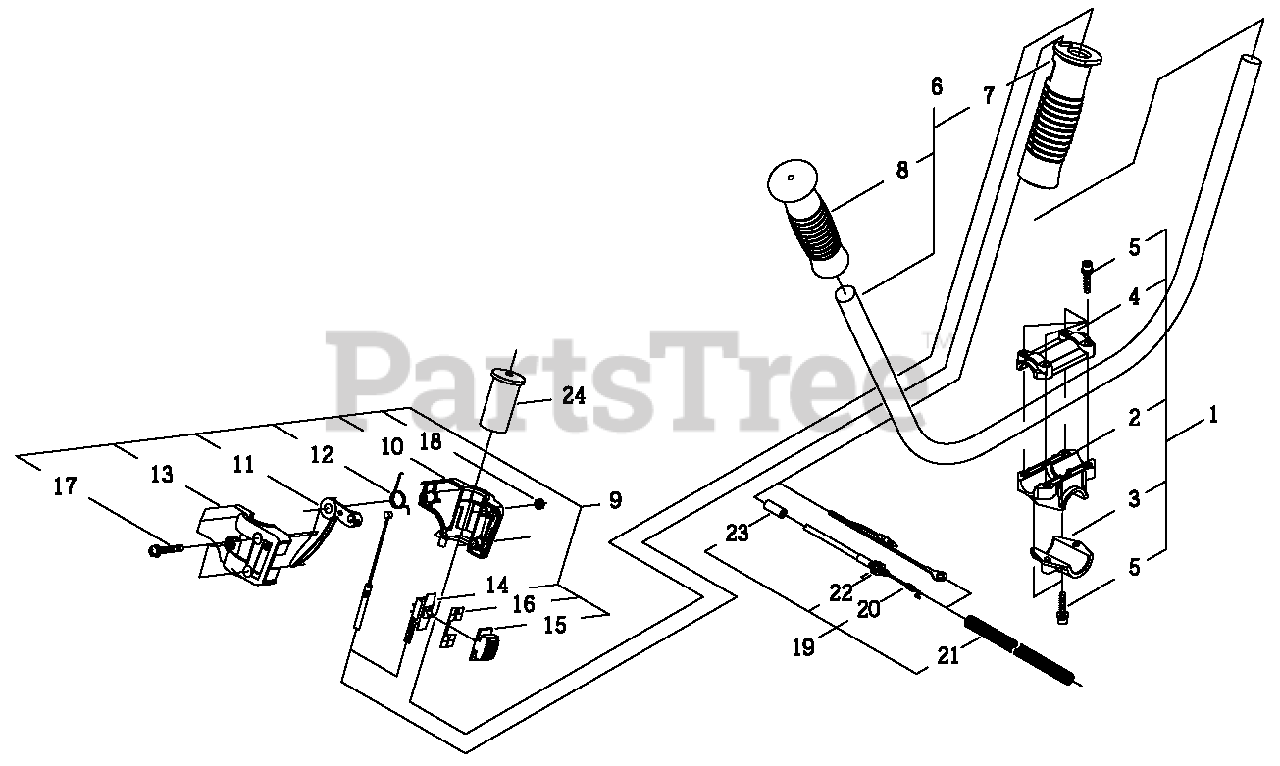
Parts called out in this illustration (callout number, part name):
1	HANDLE BRACKET KIT
2	HANDLEBAR BRACKET - LOWER
3	BRACKET, MOUNTING
4	HANDLEBAR BRACKET - UPPER
5	SCREW - 5X25
6	HANDLE ASSY
7	GRIP, HANDLE - RIGHT
8	GRIP, HANDLE - LEFT
9	THROTTLE CONTROL KIT
10	BRACKET - RIGHT
11	TRIGGER, THROTTLE
12	SPRING
13	BRACKET - LEFT
14	IGNITION SWITCH ASSY
15	KNOB
16	PLATE, SWITCH
17	SCREW - 5X30
18	NUT - 5
19	THROTTLE CABLE ASSY
20	CABLE, THROTTLE
21	TUBE
22	NUT - 6
23	PIPE
24	SPACER
